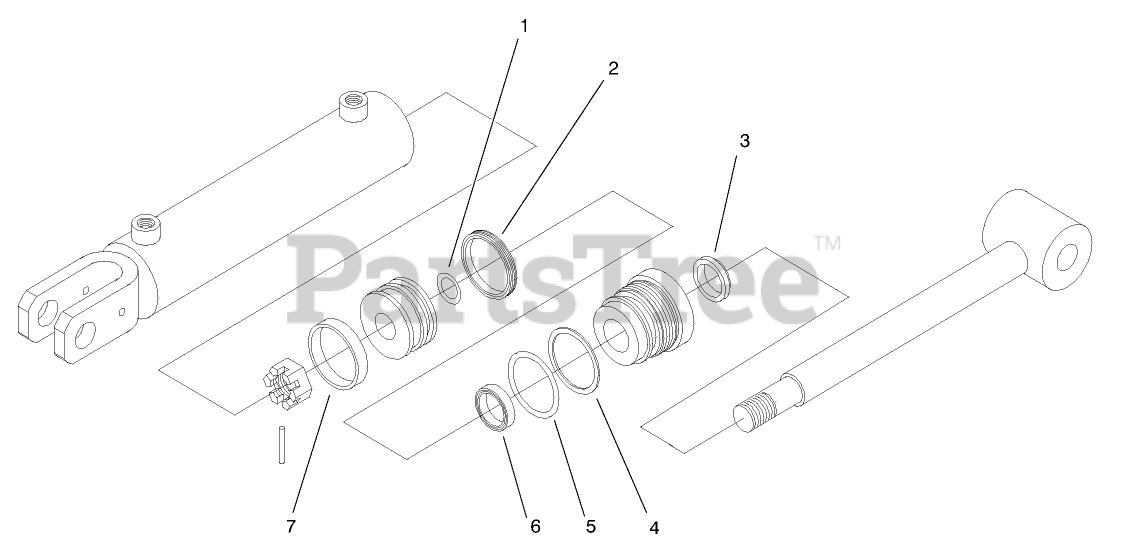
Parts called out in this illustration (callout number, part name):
2	PSP Seal
3	Rod-Wiper
4	Backup Wiper
6	Polypak
7	Ring-WEAR
